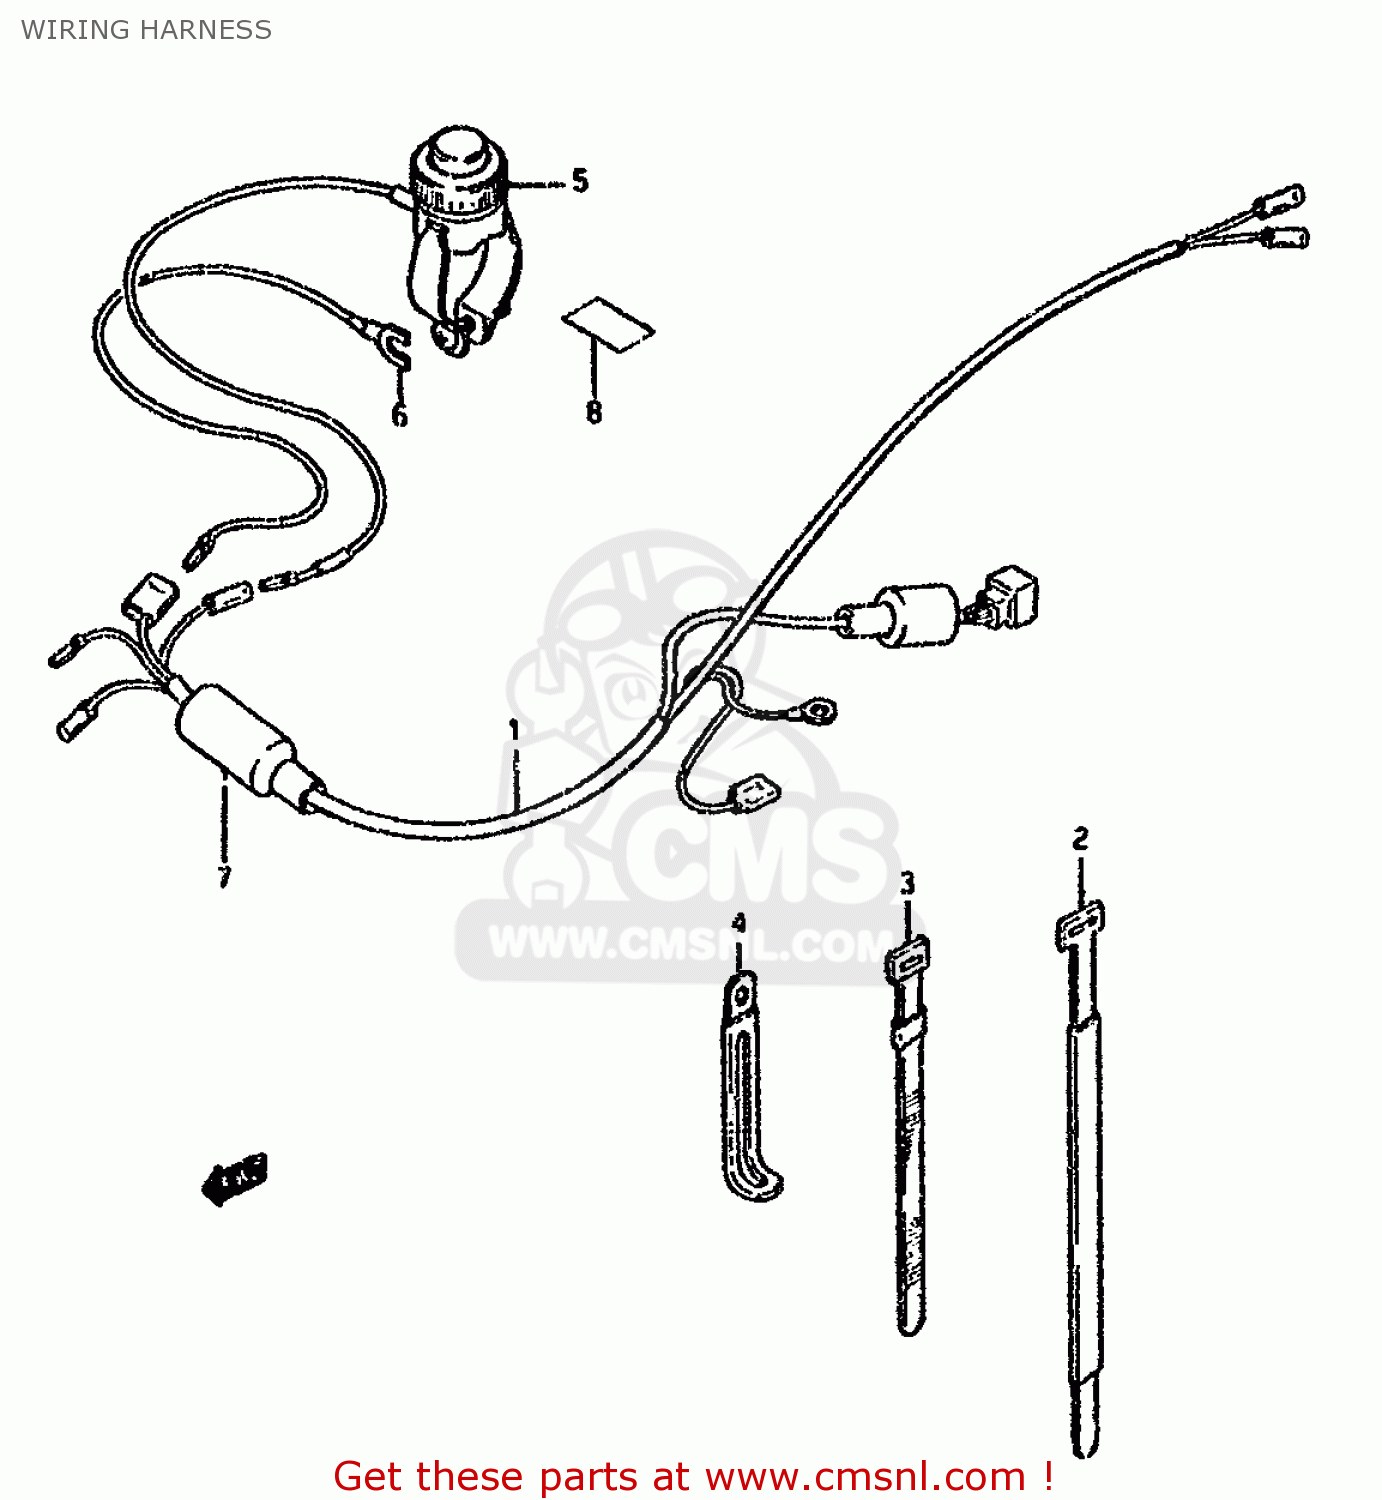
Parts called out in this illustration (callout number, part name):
1	HARNESS,WIRING
2	CLAMP
3	CLAMP(L:120)
4	CLAMP(L:45)
5	SWITCH ASSEMBLY
6	WIRE,LEAD
7	COVER,WIRE
8	LABEL (ENGINE STOP)
